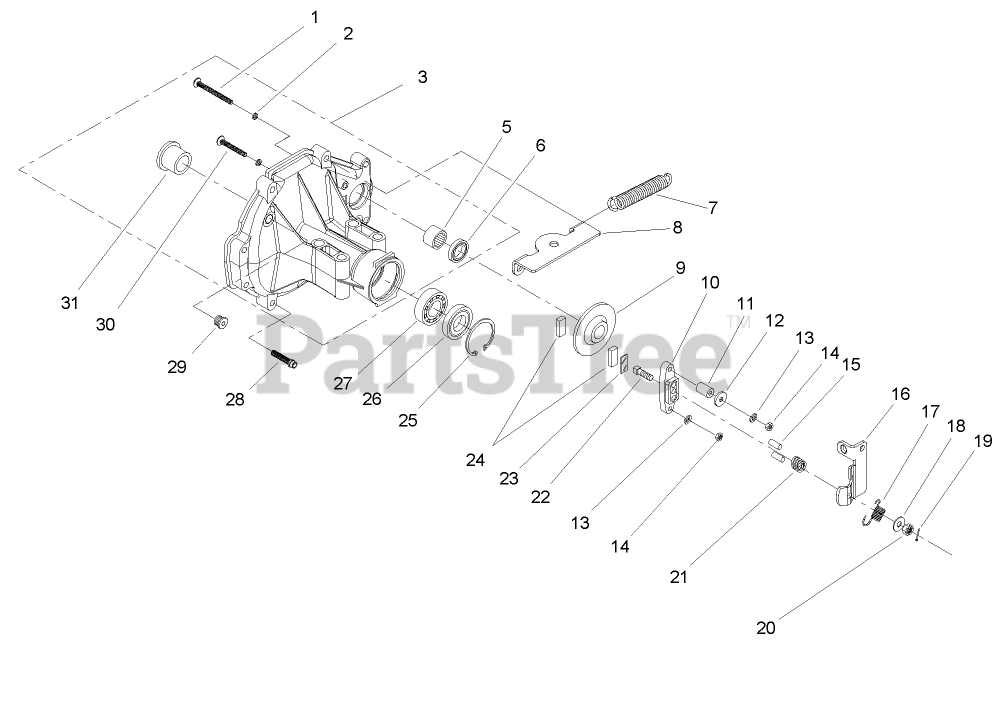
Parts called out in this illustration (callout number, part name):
2	O-RING
3	RH HOUSING ASM
5	BEARING-NEEDLE
6	SEAL-LIP
7	SPRING-RETURN
8	BRACKET-CRANK, BELL
9	DISK-BRAKE
10	YOKE-BRAKE
11	SPACER
12	WASHER
13	WASHER-LOCK
15	PIN-BRAKE
16	ARM-BRAKE
17	SPRING-ARM, BRAKE (BIAS)
18	WASHER-PIVOT
19	PIN-COTTER
20	NUT-CASTLE
21	SPRING-BRAKE, ANTI DRAG
22	BOLT-SQH
23	PUCK-PLATE
24	PUCK-BRAKE
25	RING-RETAINING
27	BEARING-BALL
28	SCREW-TTH
29	PLUG-THREAD, STRAIGHT
31	BEARING-FLANGE
